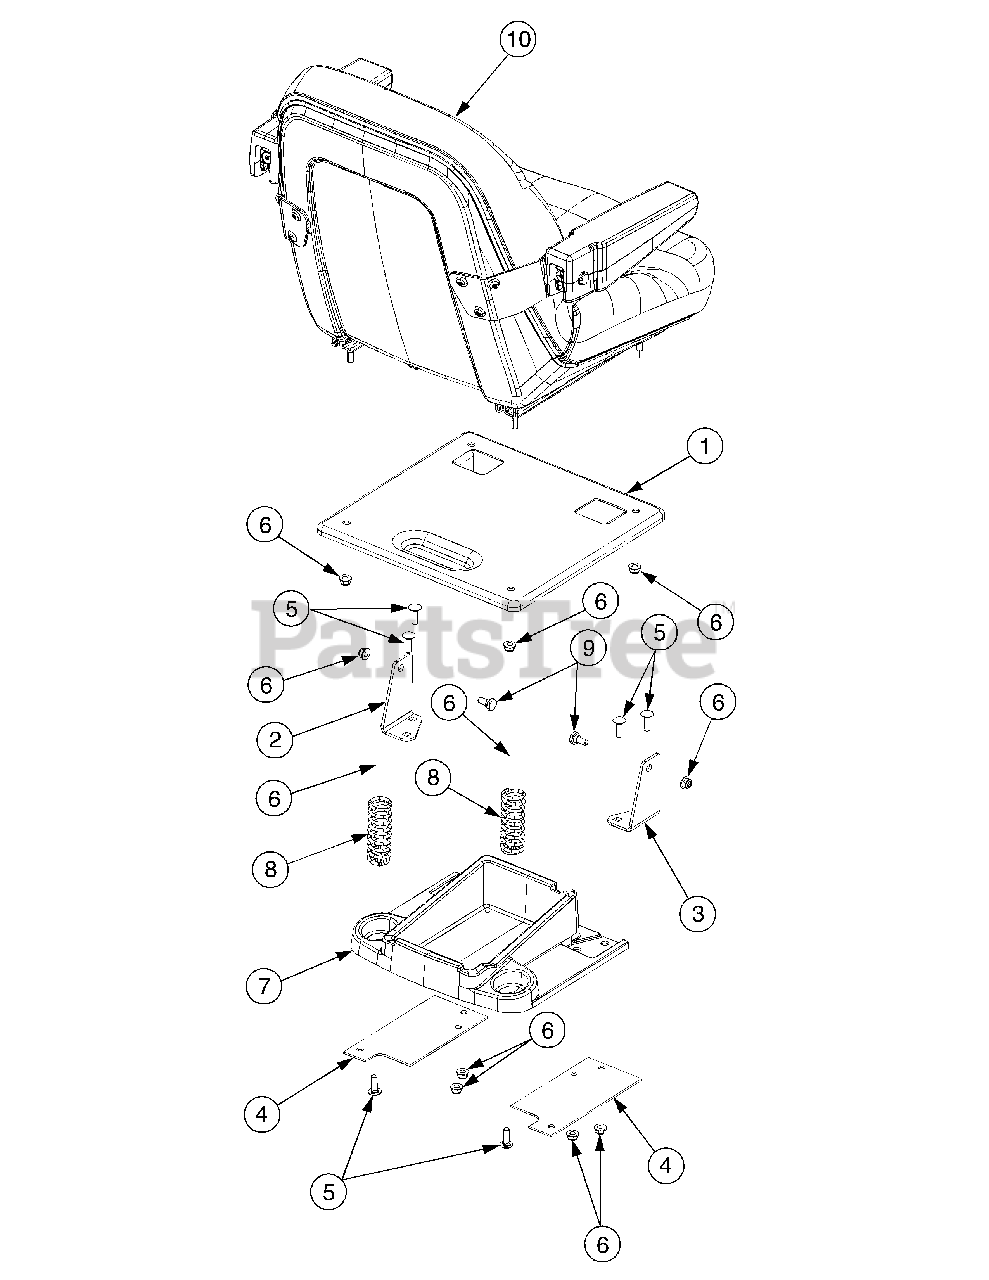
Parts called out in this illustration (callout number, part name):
1	Graphic, Seat Adjuster
6	Nut, Hx Insert Flnge Lck, 5/16-18 GrF
7	Tray, Tool
7	Graphic, Seat Adjust
8	Spring, Compression
9	Bolt, Shoulder
10	Seat, High Back w/Arm Rests
